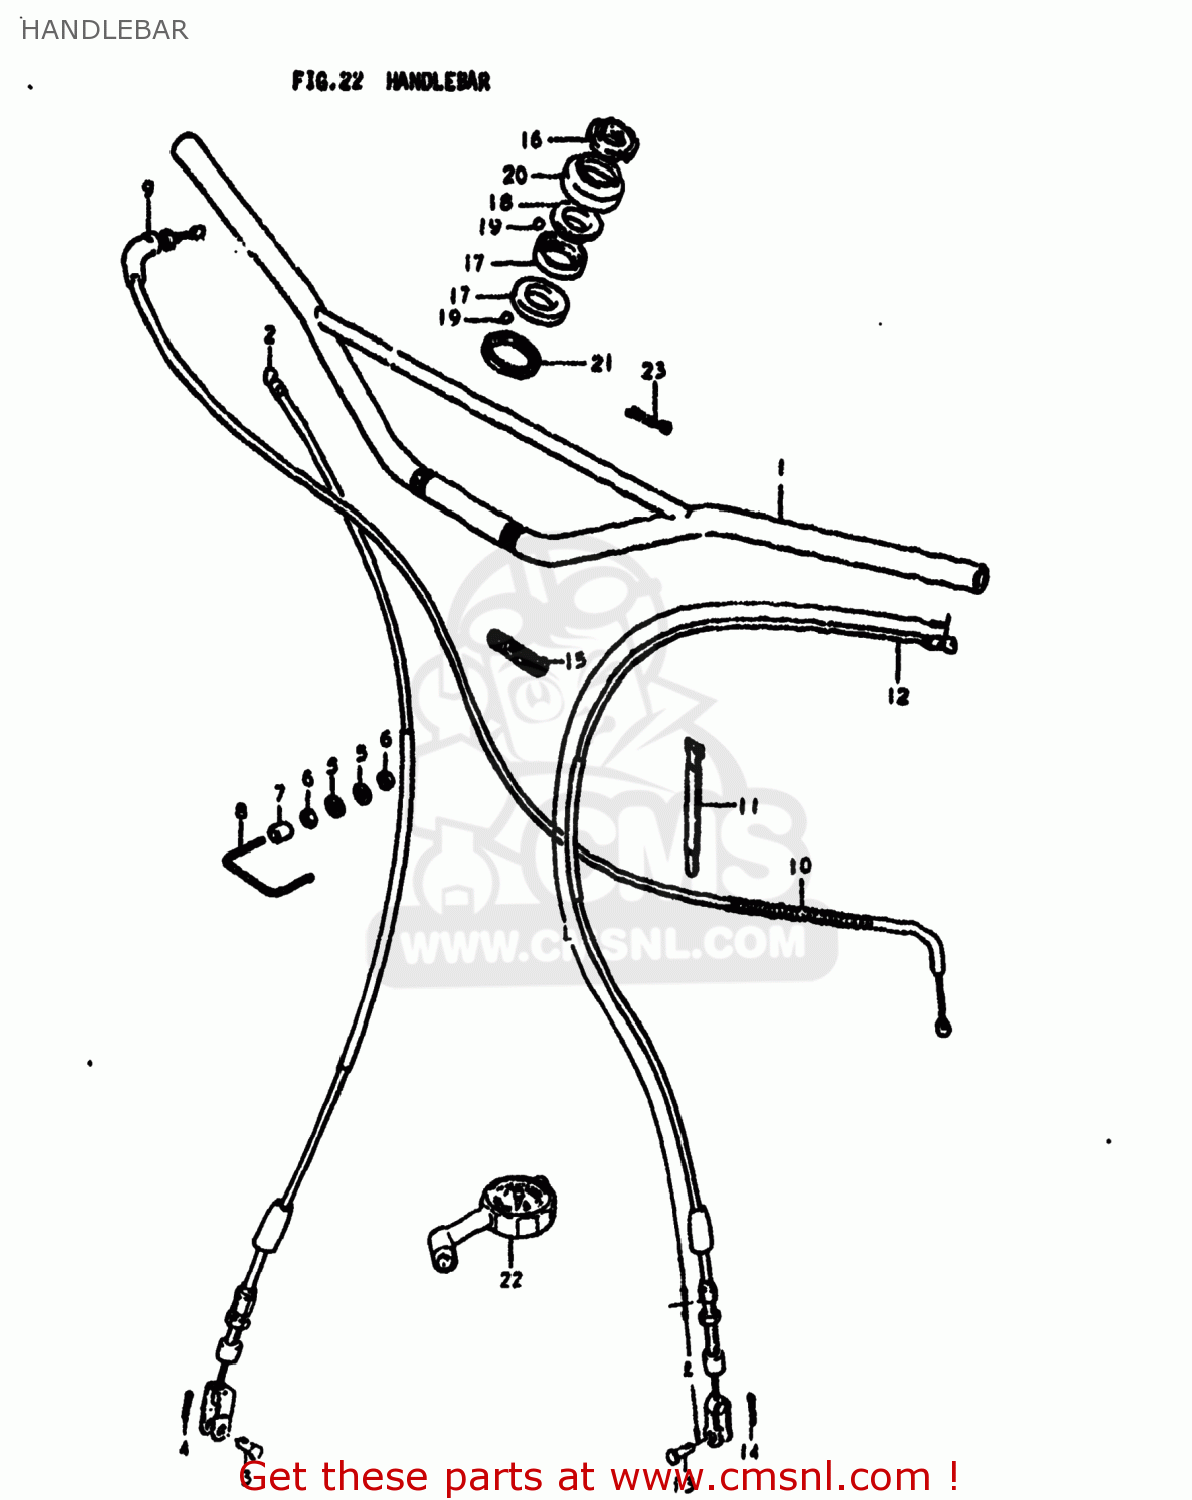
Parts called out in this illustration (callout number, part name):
1	HANDLEBAR
2	CABLE ASSEMBLY,FRONT BRAKE
3	PIN(L:17.5)
4	PIN
5	WASHER
6	NUT 3MM
7	BUSHING
8	CLAMP,CABLE
9	CABLE ASSEMBLY,THROTTLE
10	PROTECTOR,CABLE
11	CLAMP
12	CABLE ASSY,CLUTCH
13	PIN(L:13)
14	PIN
15	CLAMP L:35
16	NUT,STEERING STEM
17	RACE,STEERING,INNER,UPPER
18	RACE,STEERING,OUTER,UPPER
19	BALL
20	SEAL,STEERING UPR DUST
21	DUST SEAL,STEERING HEAD
22	GAUGE ASSY,AIR PRESSURE
23	PIN 20X20
